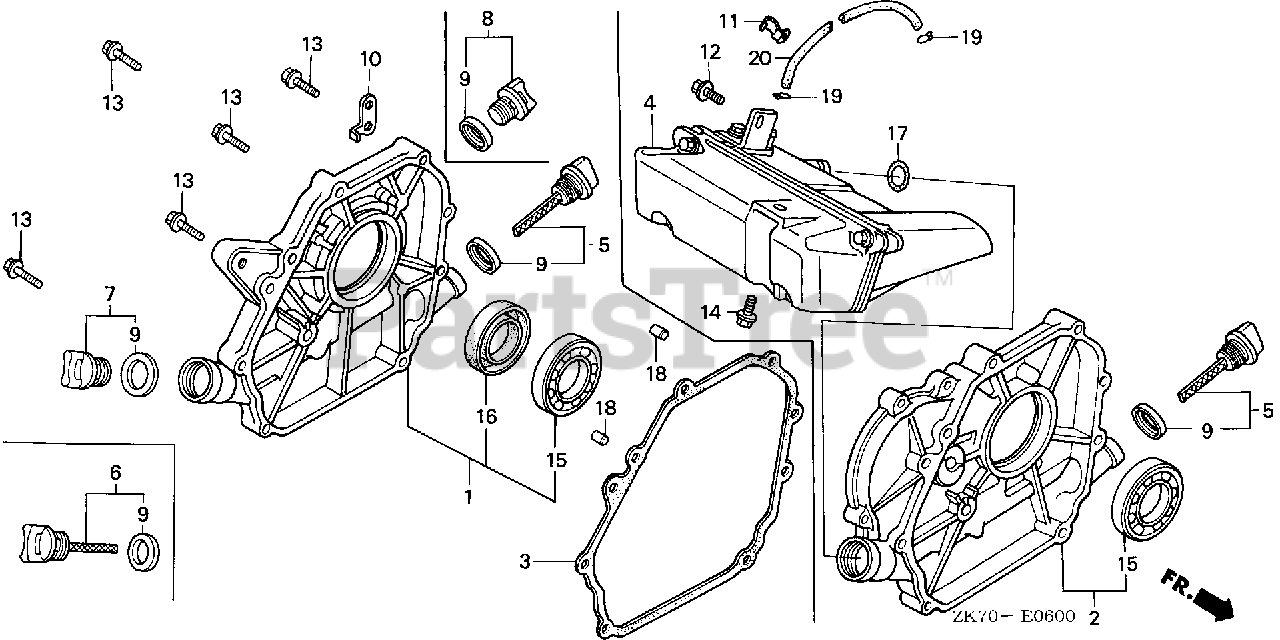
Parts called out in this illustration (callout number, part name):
1	COVER ASSY., CRANKCASE
3	GASKET, CASE COVER
5	CAP ASSY., OIL FILLER
7	CAP ASSY., OIL FILLER
9	GASKET, OIL FILLER CAP
13	BOLT, FLANGE (6X28) (CT200) Use up to Engine SN 1530314.
15	BEARING, RADIAL BALL (62/22)
16	OIL SEAL (22X41X6)
18	PIN A, DOWEL (8X14)
